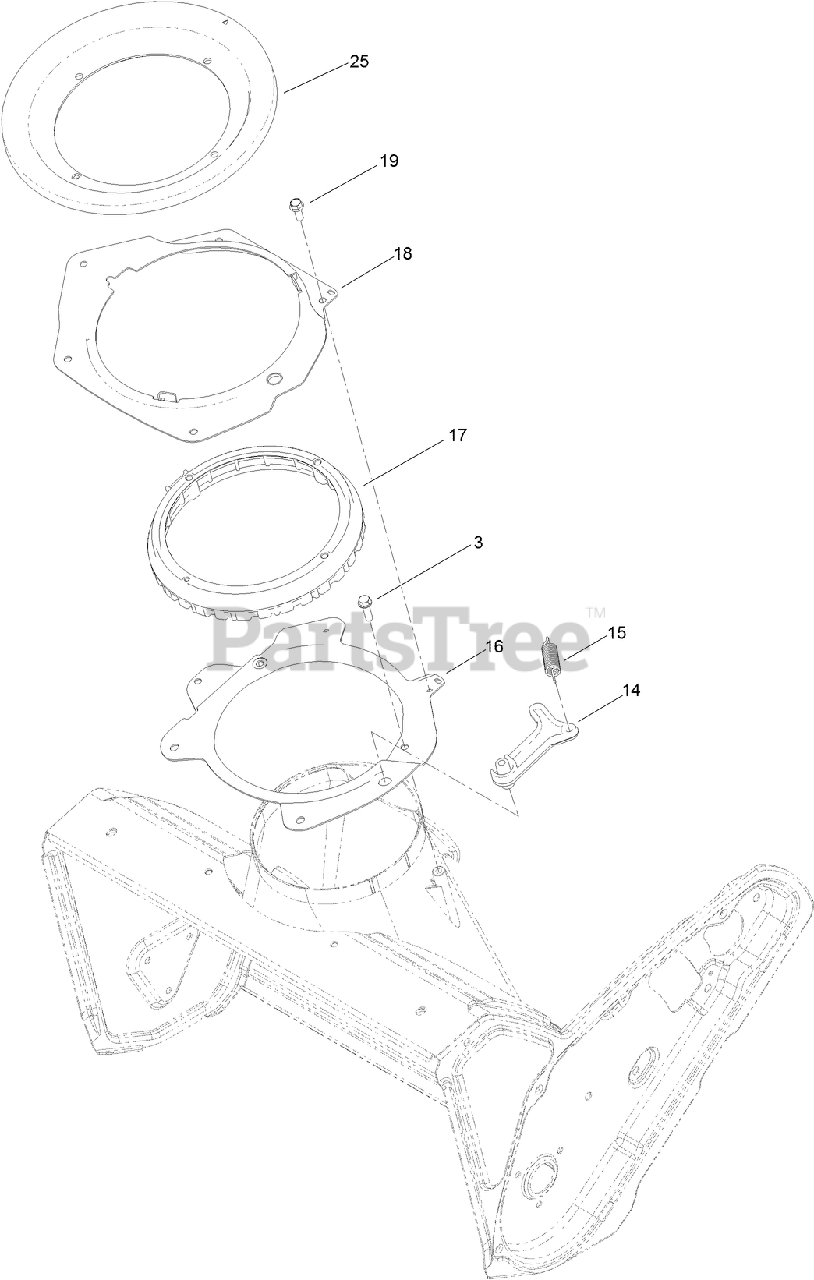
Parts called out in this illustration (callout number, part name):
3	SCREW-HWH
14	PAWL-DETENT
15	SPRING-EXTENSION
16	RING-SUPPORT, CHUTE
17	RING-CHUTE, DETENT
18	RETAINER-RING, CHUTE
19	SCREW-HWH
25	SEAL-RING, CHUTE
